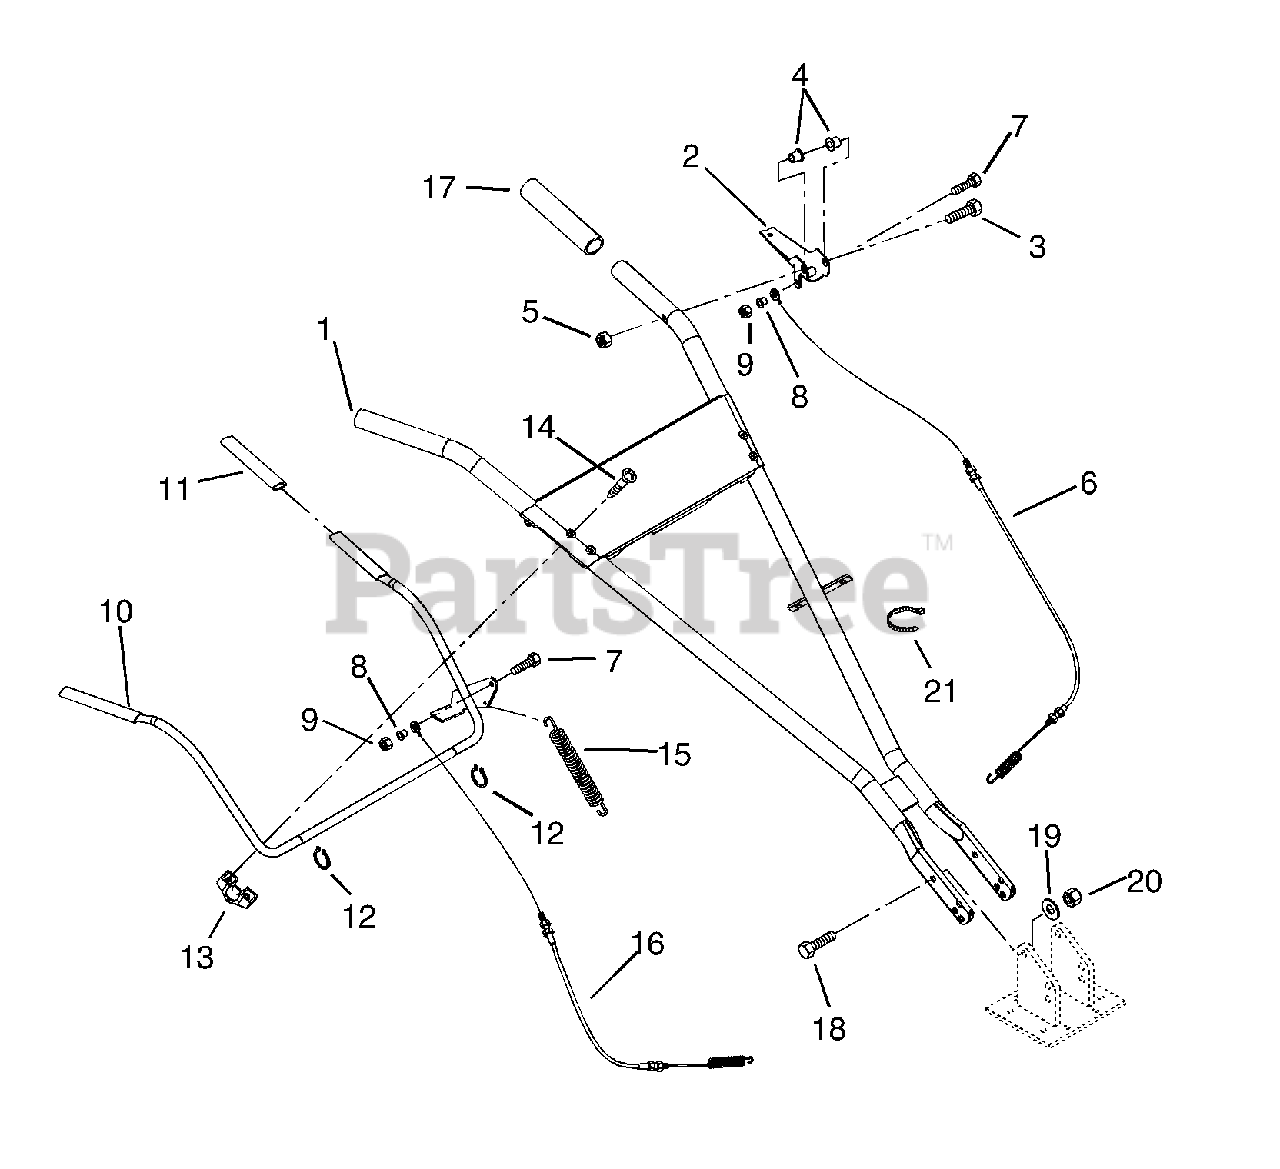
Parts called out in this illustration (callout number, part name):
1	HANDLEBAR
2	HANDLE, REVERSE
3	@BLT-HEX .31-18X2.25 GR5 YWZC
4	BSHG-FLG .325X.465X.333X.685
5	@NUT-LK-CTR .31-18 YWZC
6	CABLE, REV. SER 18"
7	@BLT-HEX .25-20X1.00 GR5 YWZC
8	BSHG-FLG .253X.373X.385X.500
9	@NUT-LK-CTR .25-20 YWZC
10	BAIL, FWD
11	GRIP, TILLER - OPC
12	RG-RTNG-EXT .500X.042 (E)
13	PIVOT, BAIL
14	SCR-TAP 12-24X1.50 CROVH YZ BT
15	SG-TENS .051X.50X5.12 WLD 10.4
16	CABLE, FWD. SER. 18"
17	HANDLEGRIP
18	@BLT-HEX .38-16X1.00 GR5 YWZC
19	@WSHR-FL-STL.438X1.00X.083 YWZ
20	@NUT-LK-CTR .38-16 YWZC
21	TIE WRAP, BLACK LG 7.31
